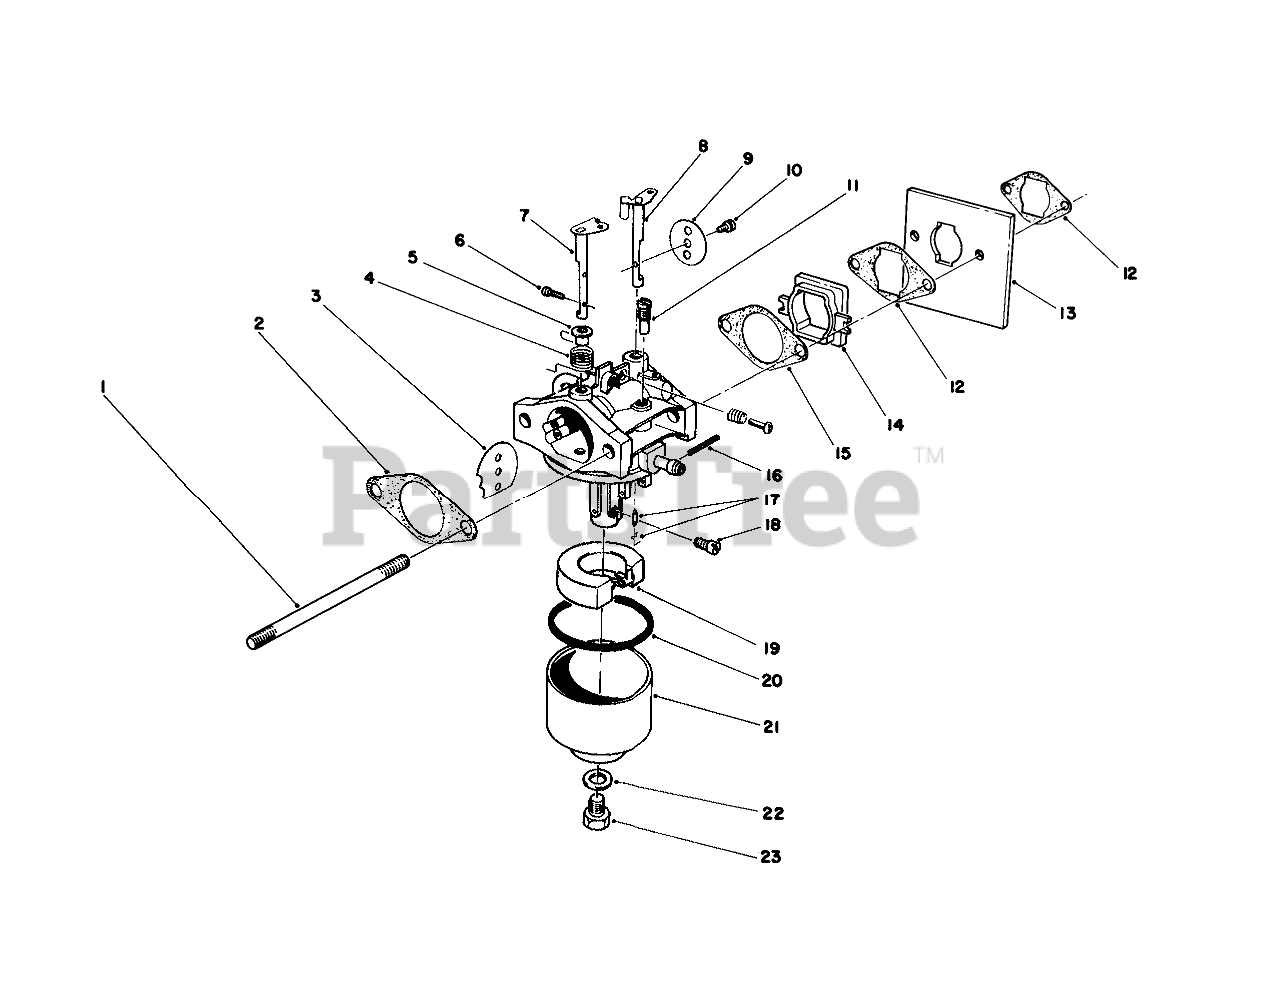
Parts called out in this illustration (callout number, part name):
1	CARB STUD BOLT
2	GASKET-AIR CLEANER
3	PLATE
3	CHOKE VALVE
4	SPRING
5	BUSHING
6	SCREW
7	SHAFT-CHOKE
8	SHAFT
9	PLATE
10	Screw-Throttle
11	PILOT JET
12	GASKET
13	SHIELD
14	INSULATOR
15	GASKET-CARB
16	Pin
17	NEEDLE VALVE ASM
17	NEEDLE
18	MAIN JET (76.3)
19	FLOAT
20	GASKET
21	Bowl-Float
22	GASKET
23	Bolt
